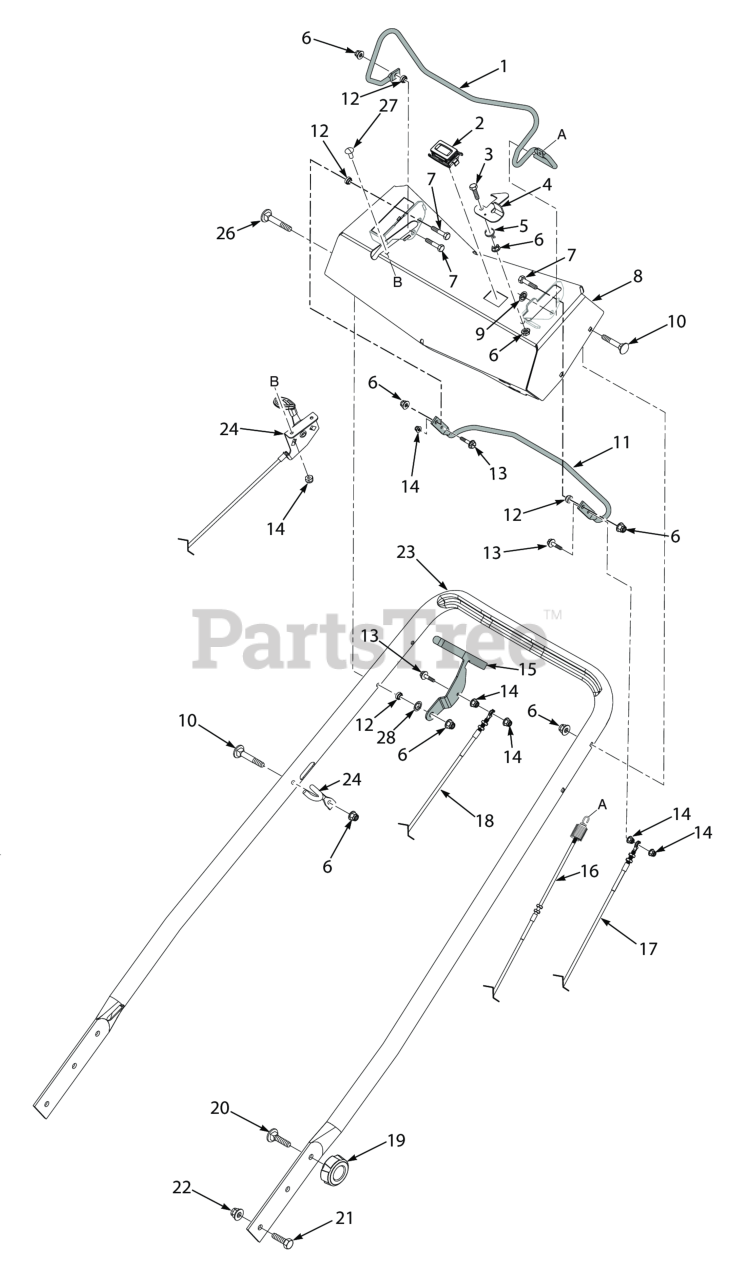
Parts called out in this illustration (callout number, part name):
1	Control, Deck
2	Hourmeter
3	Capscrew, Hex Head 1/4-20 x 1"
4	Latch, PTO
5	Spring, Hood Latch
6	Nut, Flanged Elastic Stop 1/4-20
7	BOLT, HEX HEAD, 1/4-20 X 3/4 GR.5
8	Instrument Panel w/Decal
9	Nut, Push-On 5/16-18
10	Bolt, Carriage 1/4-20 x 2"
11	Control, Drive
12	Pivot
13	Screw, #10-24 x 1" HD Slotted
14	Nut, Elastic Stop #10-24
15	Bracket, Brake Handle
16	Cable, Deck
17	Cable, Drive
18	Cable, Brake
19	Knob, 3/8-16 x 2.48 OD
20	Bolt, Carriage 3/8-16 x 3/4"
21	Screw, 3/8-16 x 3/4"
22	Nut, Flange Elastic Stop Nut, 3/8-16
23	Handle
24	Cable, Throttle
25	Guide, Pull Rope
26	Bolt, Carriage 1/4-20 x 2-1/2" Full Thread
27	Bolt, Carriage #10-24 x 1/2"
28	Washer, Curved
